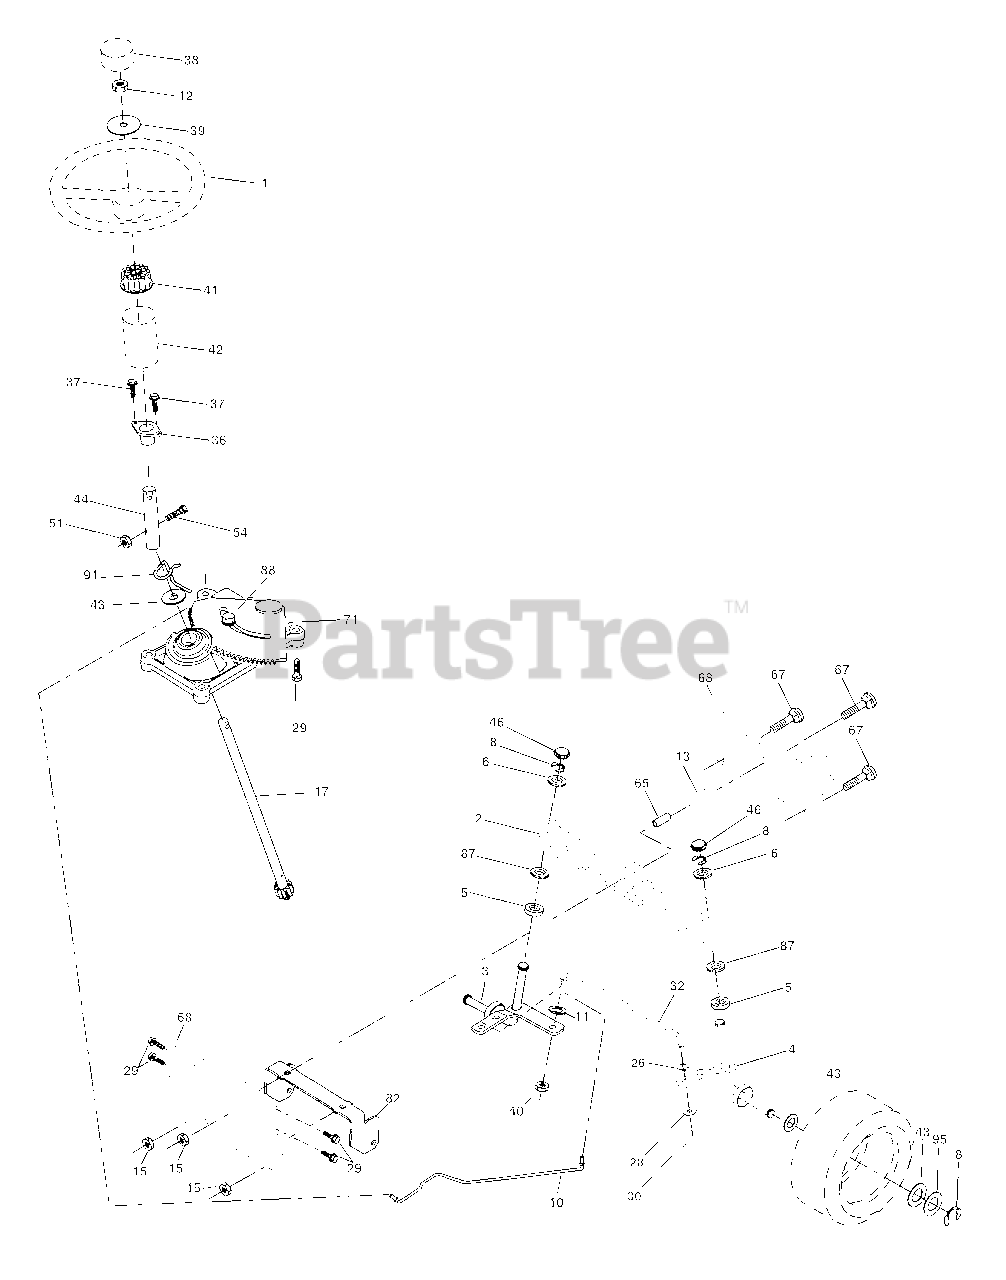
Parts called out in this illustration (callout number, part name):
1	Wheel Steering
2	Axle Asm Cast Iron LT
3	Spindle Asm LH
4	Spindle Asm RH
5	Bearing Race Thrust Harden
6	Washer 25/32 x 1-5/8 x 16 Ga.
8	Ring Klip #t5304-75
10	Link Drag
11	Washer Lock Hvy Hlcl Spr 3/8
12	Nut Hex Jam Toplock 1/2-20 unf
13	Spacer Brg Axle Front
15	Nut Hex Flange Lock
17	Shaft Asm Steering
26	Bushing Link Drag
28	Washer 13/32 x 7/8 x 16 Ga.
29	Screw 3/8-16 x .75
30	Pin Cotter 1/8 x 3/4
32	Rod Tie
36	Bushing Strg
37	Screw
38	Insert Cap Strg Wh
39	Washer 9/16 x 1 1/20 x 11 Ga.
40	Crownlock nut
41	Adaptor Wheel Strg
42	Boot Steering Dash
43	Washer 25/32 x 1 1/4 x 16 Ga.
44	Extension Steering Shaft
46	Cap Spindle Fr Top Blk
51	Nut Crownlock 1/4-28
54	Bolt Hex 1/4-28 unf x 1-1/4 Gr. 8
65	Spacer Brace Axle
67	Bolt RDHD SQNK 3/8-16 x 2 1/4
68	Axle, Brace
71	Steering Asm
82	Bracket Susp Chassis Front
87	Washer Flat .781 x 1-1/2 x .14
88	Bolt Shoulder 7/16-20 unc
91	Clip Steering
95	Washer Harden .739 x 1.637 x 060
